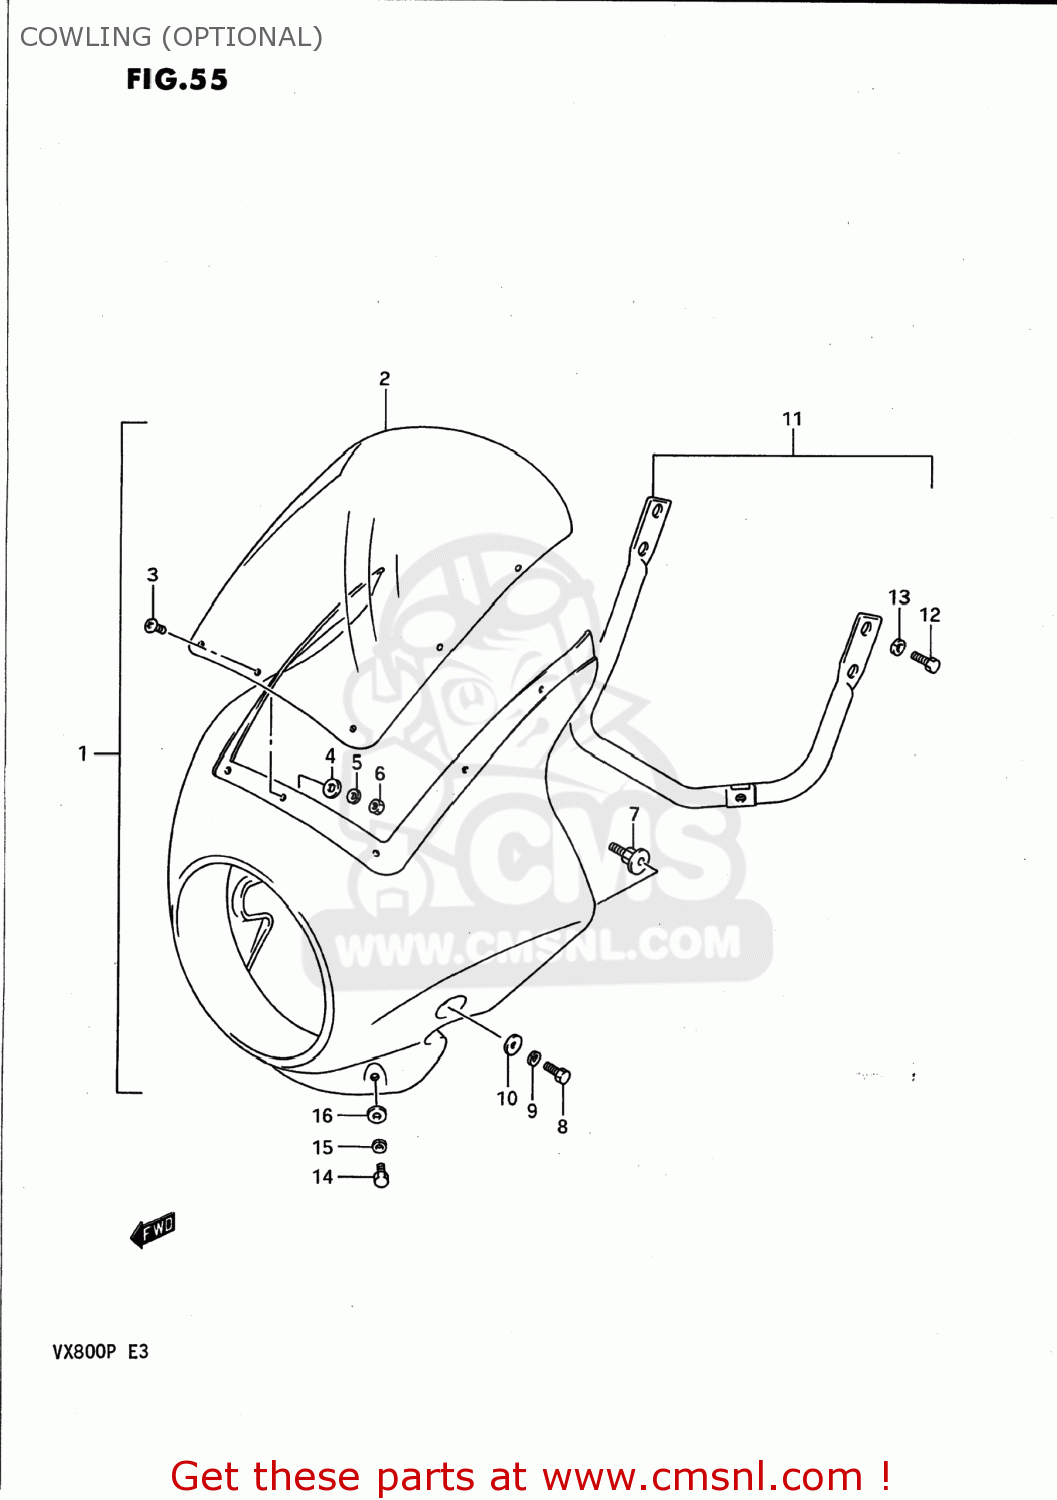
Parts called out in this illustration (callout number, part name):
1	UPPER COWLING SET
2	SCREEN,COWLING
3	SCREW
4	WASHER
5	LOCK WASHER
6	NUT
7	BOLT,COWLING HEADLAMP
8	BOLT
9	WASHER,LOCK
10	WASHER
11	BRACE,UPPER COWLING
12	BOLT
13	WASHER
14	BOLT
15	WASHER,LOCK
16	WASHER
